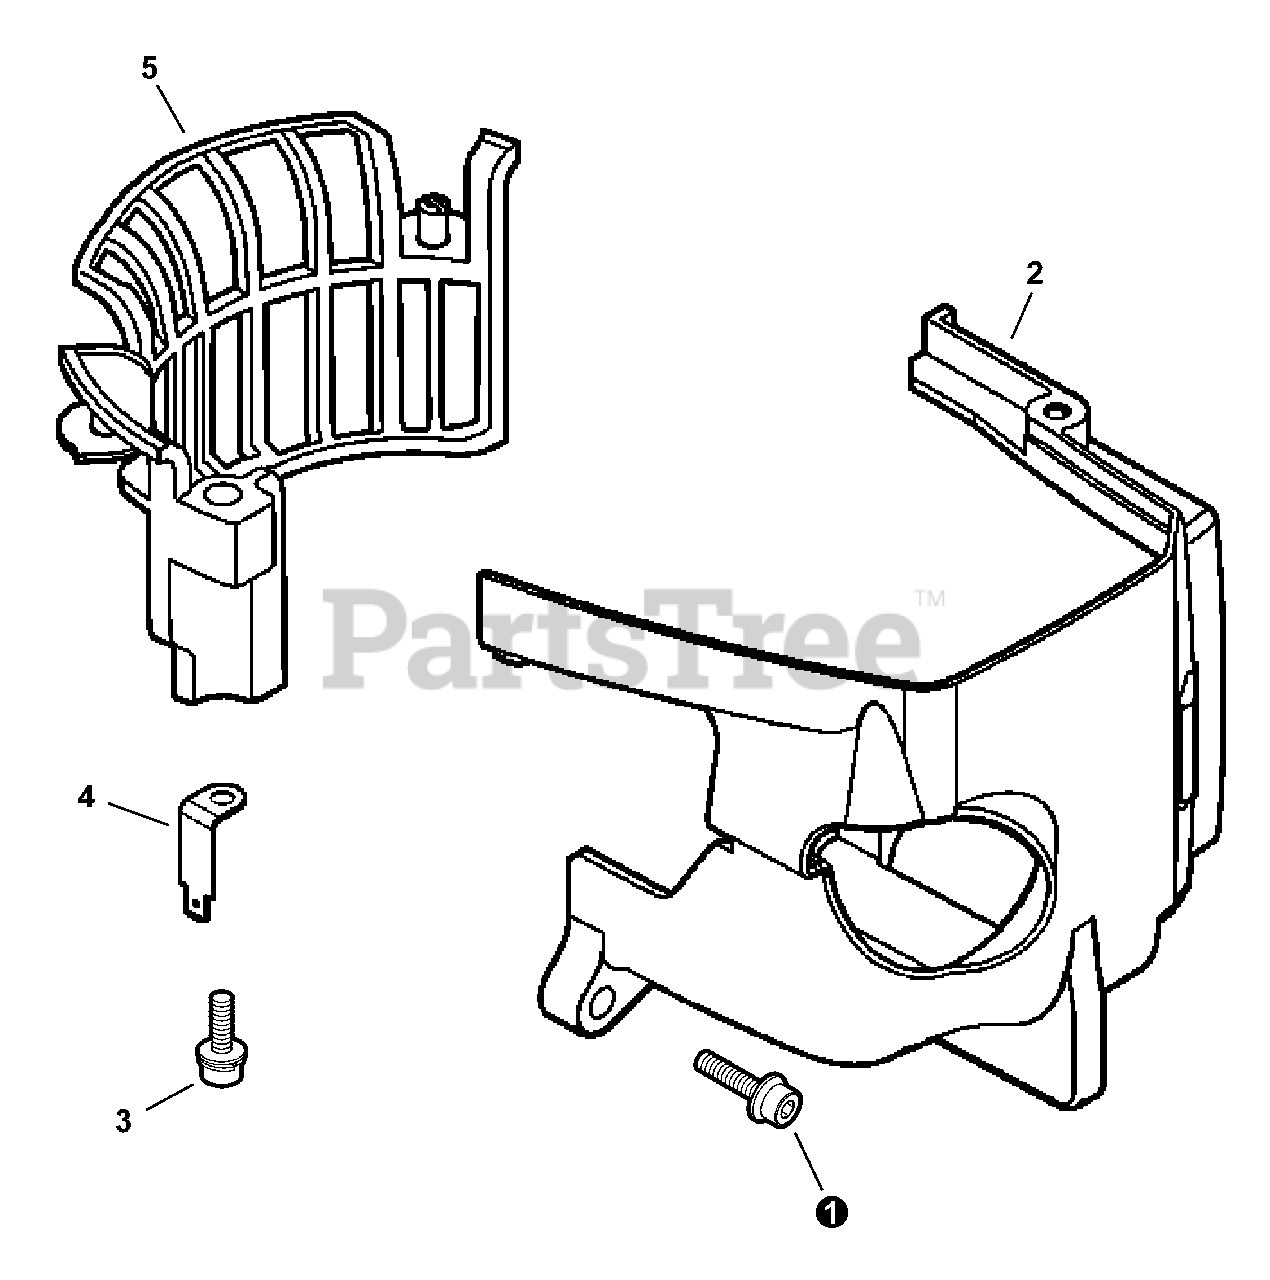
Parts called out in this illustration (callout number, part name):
1	SCREW - 5×16
2	COVER, ENGINE
3	SCREW - 5×16
4	TERMINAL - GROUND
5	GUARD, DEBRIS
